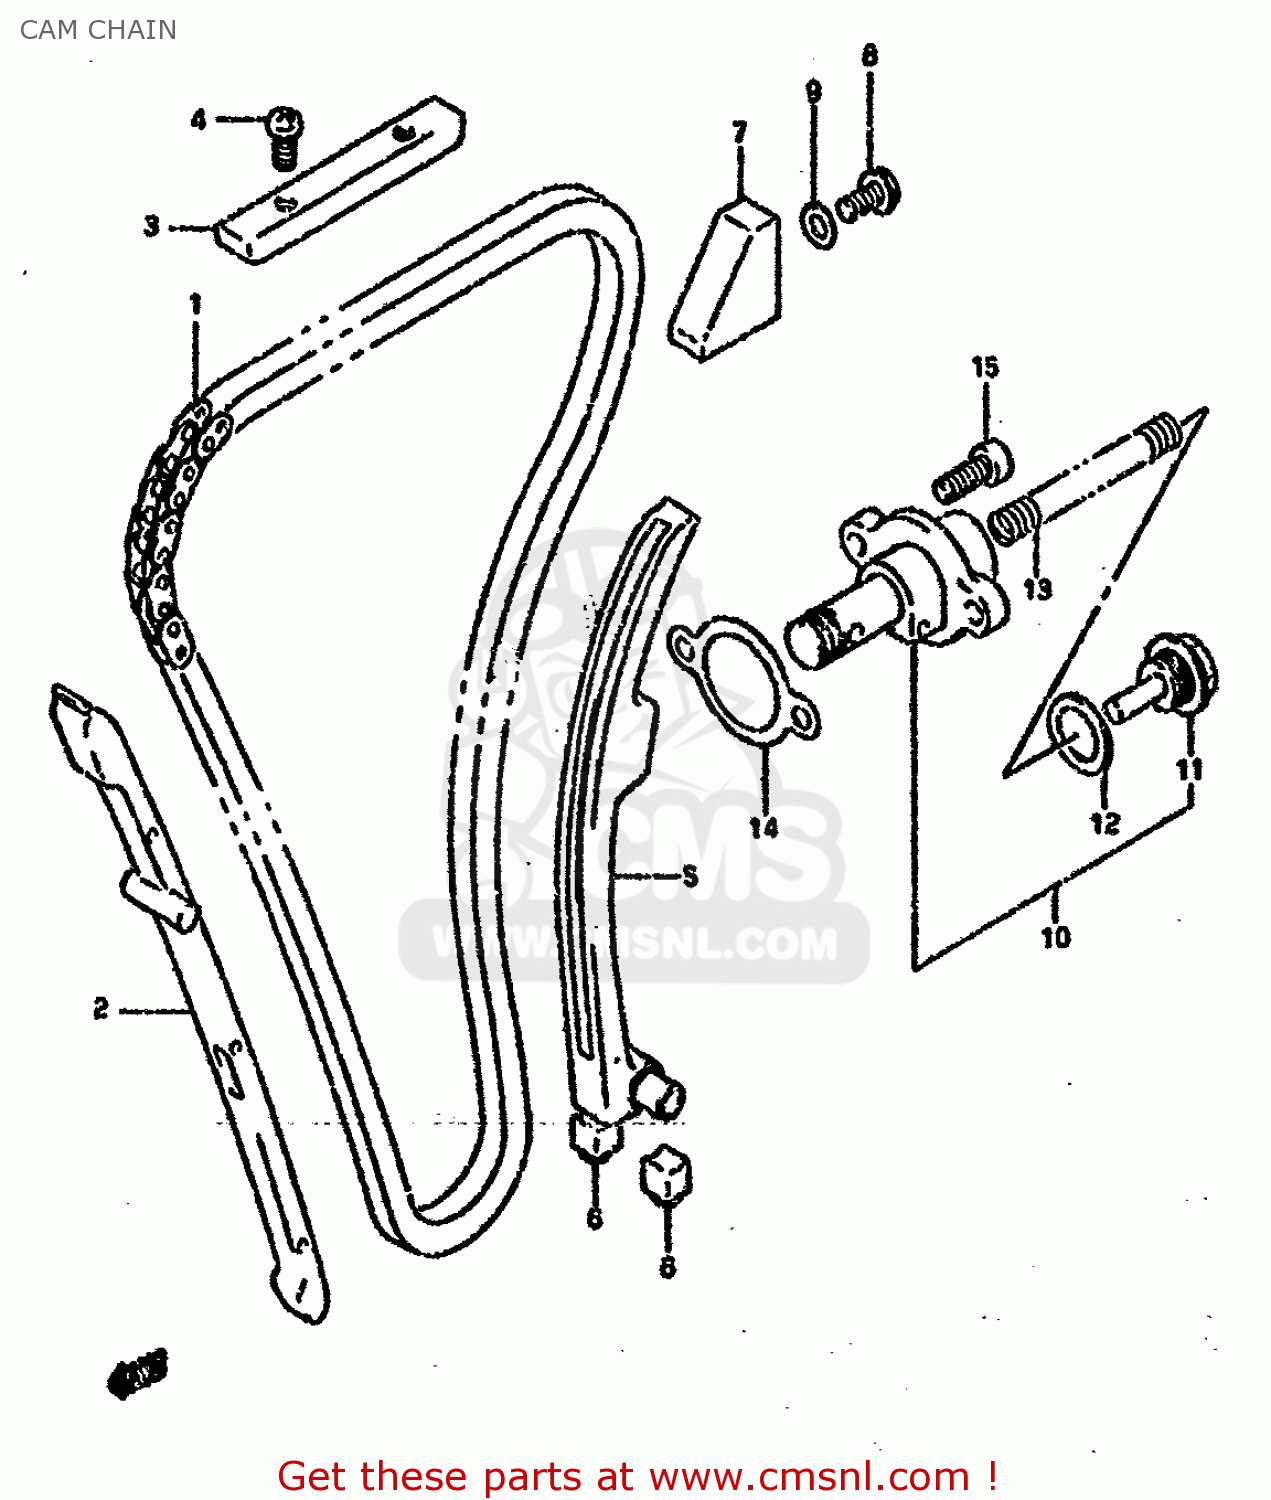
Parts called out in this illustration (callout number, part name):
1	CHAIN,CAMSHAFT DRIVE
2	GUIDE,CAM CHAIN NO.1
3	GUIDE,CAM CHAIN NO.2
4	SCREW
5	TENSIONER,CAM CHAIN
6	CUSHION,CAM CHAIN TENSIONER
7	GUIDE,CAM CHAIN NO.3
8	BOLT
9	GASKET(5.8X13X1.2) (NAS)
10	ADJUSTER ASSEMBLY,TENSIONER
11	PLUG
12	GASKET (NAS)
13	SPRING
14	GASKET,TENSIONER ADJUSTER (NAS)
15	BOLT(6X22)
